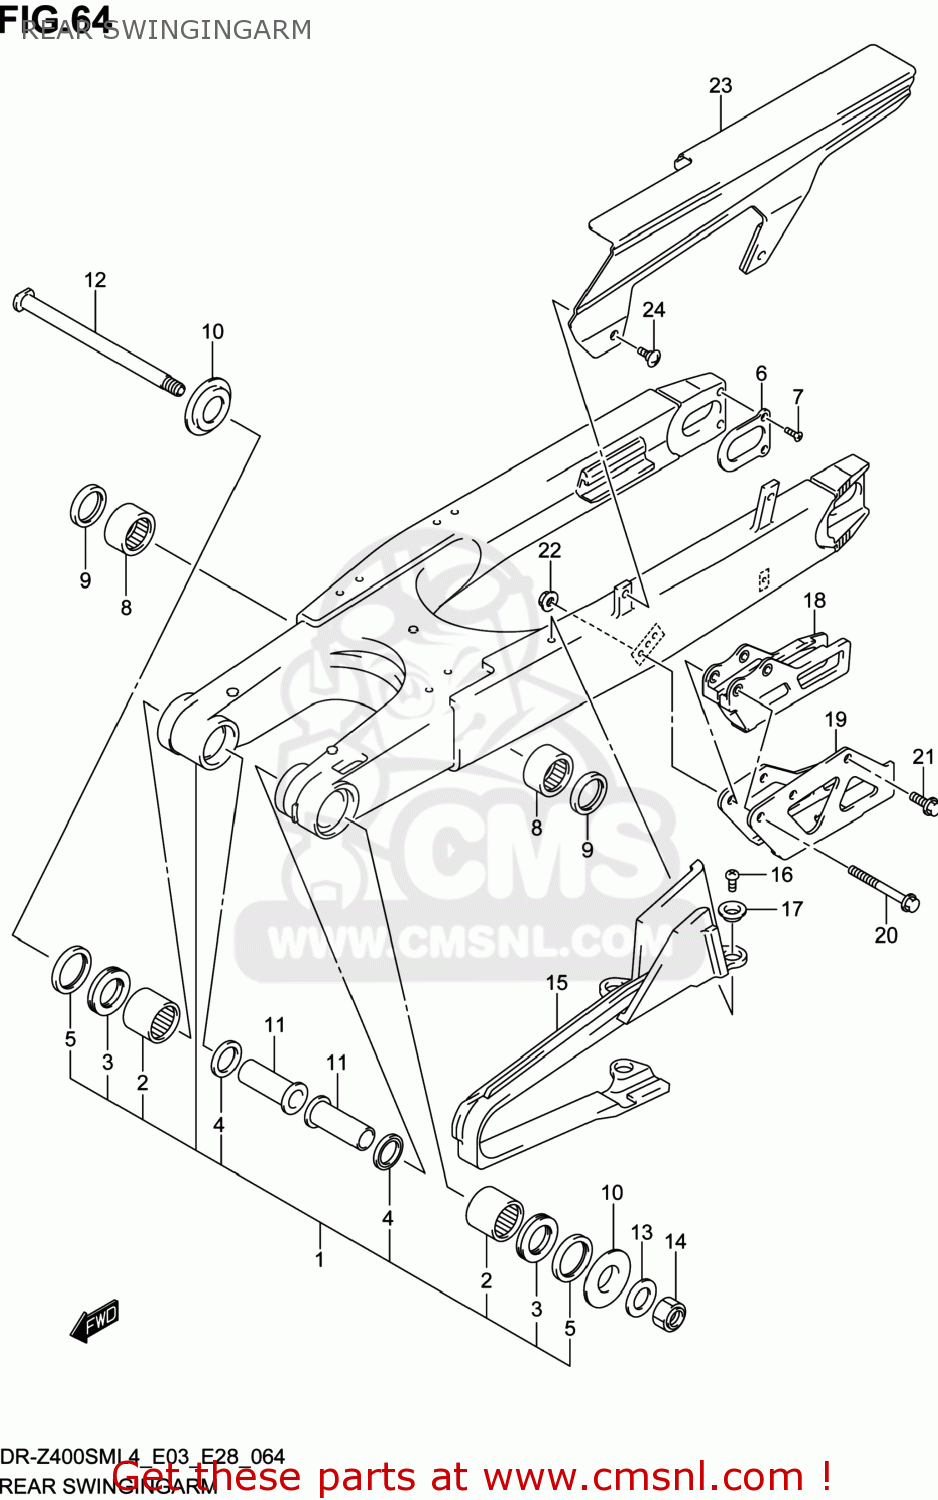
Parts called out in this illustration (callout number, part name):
1	SWINGINGARM ASSY,RR
2	BEARING(22X29X30)
3	BEARING(22X35X2)
4	SEAL,OIL(22X29X4)
5	SEAL,RR SWGARM PIVOT OUTER
6	PLATE,SWGARM REAR
7	SCREW(5X10)
8	BEARING(20X27X15)
9	SEAL,CUSHION LEVER DUST
10	SPACER,SWINGINGARM PIVOT OUTER
11	SPACER,SWGARM PIVOT INNER
12	SHAFT,RR SWINGINGARM PIVOT
13	WASHER
14	NUT
15	BUFFER,CHAIN TOUCH DEFENSE
16	SCREW
17	WASHER
18	GUIDE,CHAIN
19	PLATE,CHAIN GUIDE
20	BOLT
21	BOLT
22	NUT
23	CASE,CHAIN
24	SCREW(6X16)
